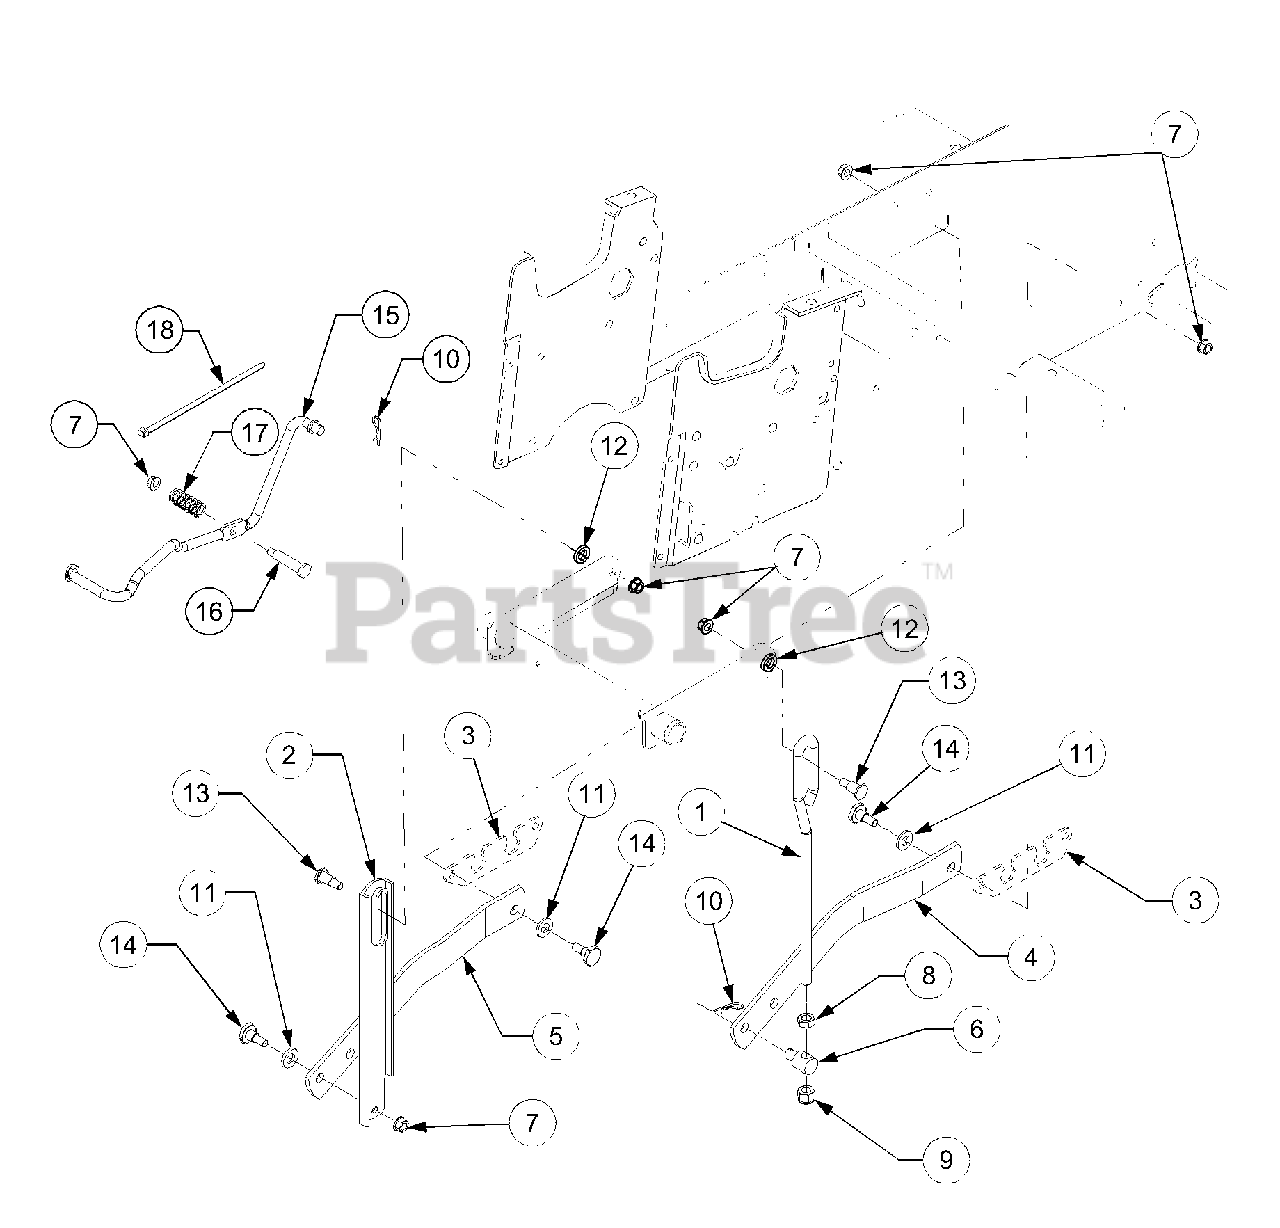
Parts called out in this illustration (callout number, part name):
1	Rod, Lift Link
7	Nut, Hex Flange Lock, 3/8-16
8	Nut, Hex Jam, 1/2-13 GR5
9	Nut, Hex Insert Lock, 1/2-13
10	Pin, Internal Cotter
11	Washer, Flat, .5 x 1.5 x .15
12	Washer, Flat, .531 x .875 x .15
13	Bolt, Shoulder
14	Bolt, Shoulder
15	Rod, Lift Assist
16	Bolt, Shoulder, 3/8-16: .5 x 2.0
17	Spring, Compression, .63 ID x 2.0
18	Tie, Cable
